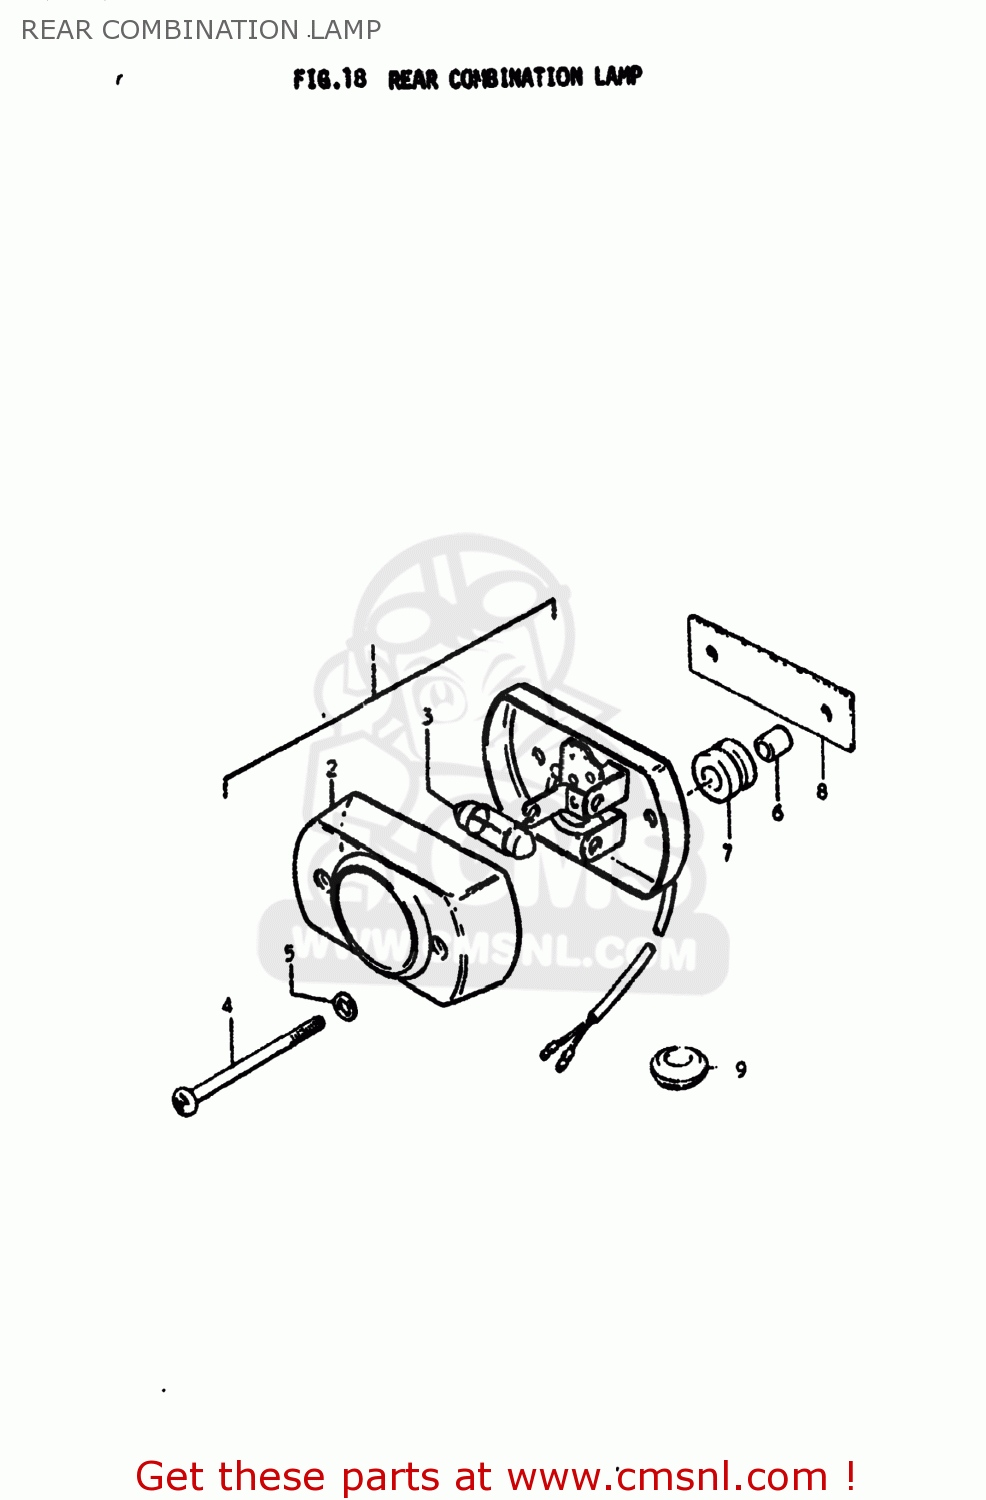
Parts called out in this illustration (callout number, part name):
1	LAMP ASSEMBLY,TAIL
2	LENS,REAR COMBINATION LAMP
3	BULB
4	SCREW,REAR COMBINATION LAMP LENS
5	WASHER,REAR COMBINATION LAMP
6	BUSHING
7	CUSHION
9	GROMMET
